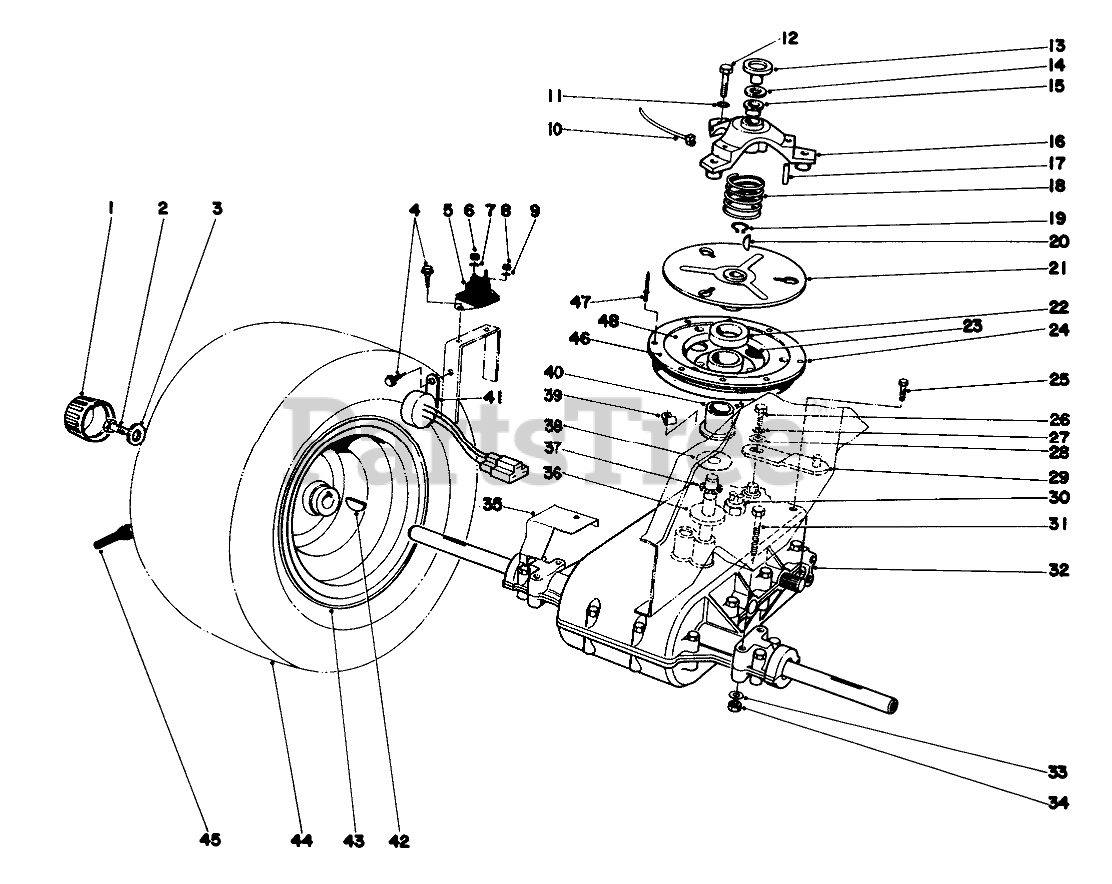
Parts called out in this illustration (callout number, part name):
1	Cap-Hub
2	Capscrew
3	SPACER-WHEEL
4	SCREW-HWH
5	SOLENOID
6	NUT-JAM, BRASS
7	Lockwasher
8	NUT-HEX
9	WASHER-LOCK
10	TIE-MOUNT, PUSH
11	WASHER-LOCK
12	SCREW-HH
13	CLUTCH CAP
14	THRUST RACE
15	BUSHING-FLANGE
16	Cover Clutch (Incl. Ref. #15& 17)
17	NEEDLE BRG
18	COMPRESSION SPRING
19	RING-SNAP, EXTERNAL
20	KEY-WOODRUFF
21	Clutch Plate
22	Felt Washer
24	Sheave Assembly (Incl.Ref. #40 & 46-48)
25	SCREW-HWHTF
26	SCREW-HH
27	WASHER-LOCK
28	WASHER-FLAT
29	SHIFT LEVER WA B
30	NEUTRAL SWITCH
31	SCREW-HH
32	Transaxle
33	WASHER-PLAIN
34	NUT-LOCK, CONE
35	GRASS SHIELD B
36	THRUST WASHER
37	NEEDLE BRG
38	THRUST WASHER
39	CLIP-FUEL LINE
40	Bushing
41	Module Interlock
42	WOODRUFF KEY
43	Rim
45	STEM-VALVE
46	CLUTCH PAD
47	RIVET-POP
48	Retainer Ring
